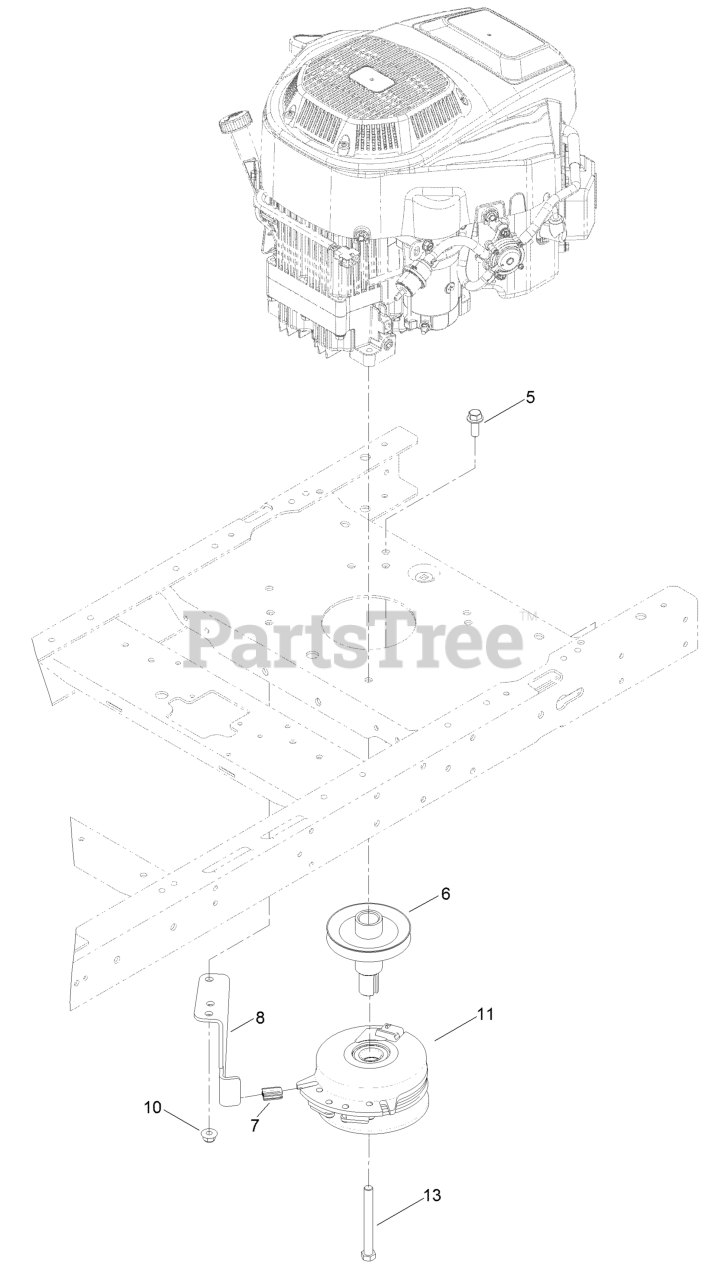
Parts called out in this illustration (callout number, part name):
5	SCREW-HHF 3/8-16 X 1
6	PULLEY-ENGINE
7	ISOLATOR-CLUTCH
8	STOP-CLUTCH (NARROW)
10	NUT-HF, NI
11	CLUTCH-ELECTRIC
13	PIN-ROLL, SLOTTED
